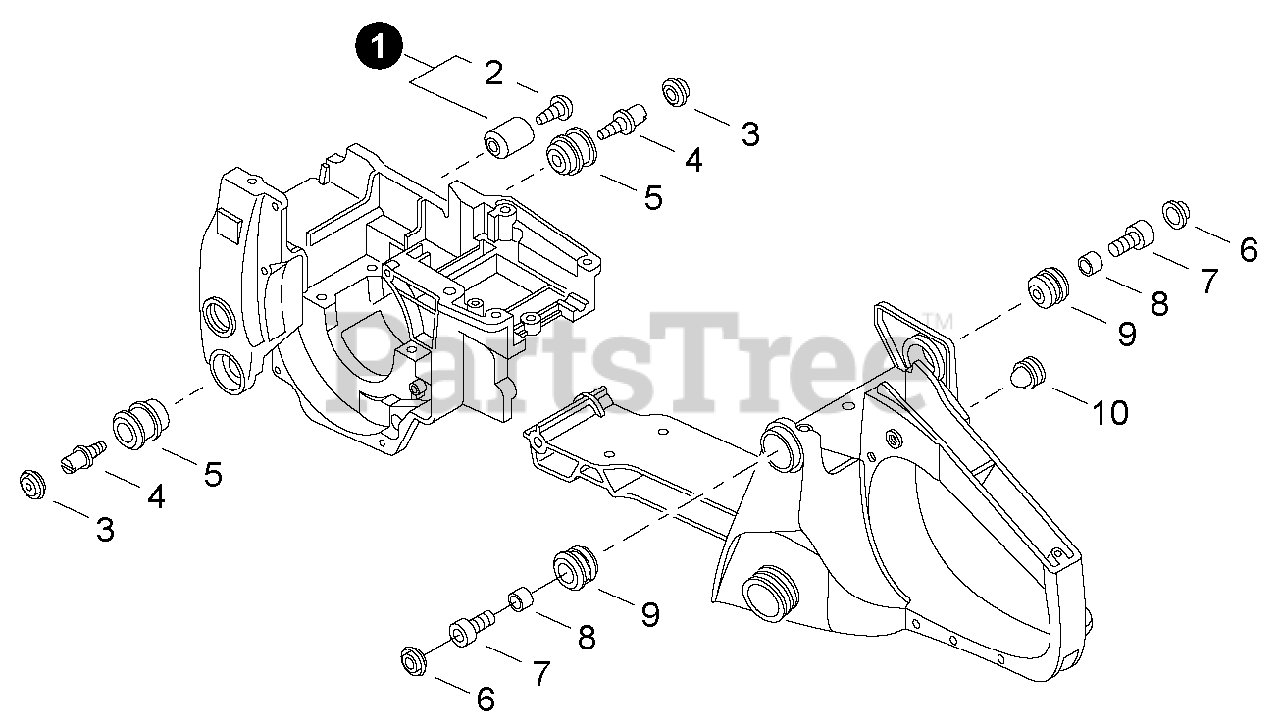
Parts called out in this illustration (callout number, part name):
1	CHAIN CATCHER KIT
2	SCREW, TAPPING 5×20
3	CAP, CUSHION
5	CUSHION 5
6	CAP, CUSHION
7	BOLT, HEX 4×20
8	COLLAR 4.2×7×9.5
